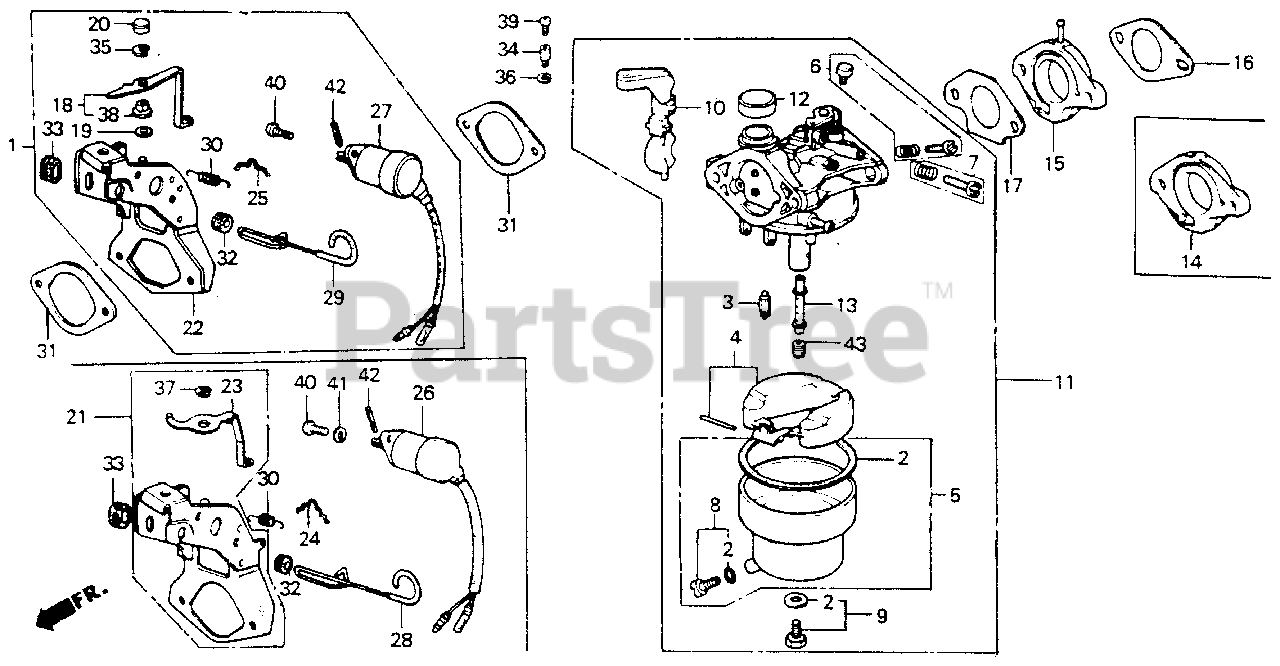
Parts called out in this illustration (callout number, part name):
2	GASKET SET
3	VALVE SET, FLOAT
4	FLOAT SET
5	CHAMBER SET, FLOAT
6	SCREW SET A
7	SCREW SET A
8	SCREW SET, DRAIN
9	SCREW SET B
11	CARBURETOR ASSY. (BB37C H)
11	CARBURETOR ASSY.
11	CARBURETOR ASSY. (BB35F E)
13	NOZZLE, MAIN (NOT AVAILABLE)
13	NOZZLE, MAIN
15	INSULATOR, CARBURETOR (NOT AVAILABLE)
16	GASKET, INSULATOR
17	GASKET, CARBURETOR
31	GASKET, AIR CLEANER
34	HOLDER, CABLE
36	CIRCLIP (5MM)
39	SCREW, PAN (4X8)
43	JET, MAIN (#95)
43	JET, MAIN (#98)
43	JET, MAIN (#92)
